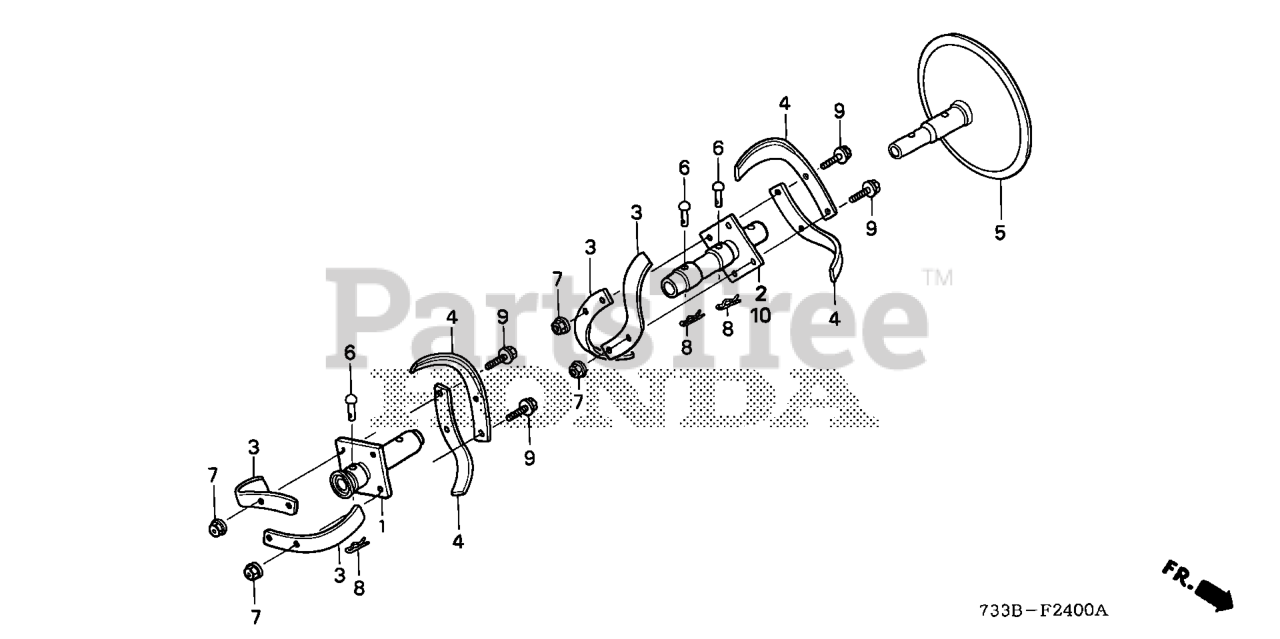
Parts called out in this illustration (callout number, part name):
1	PIPE (INNER)
2	PIPE, R. (OUTER)
3	TINE A, ROTARY
4	TINE B, ROTARY
5	DISK, SIDE
6	PIN (10X53.5)
7	NUT, FLANGE (10MM)
8	PIN, LOCK (10MM) Use from Frame SN 2149606 to 2149605.
9	BOLT, FLANGE (10X25)
10	PIPE, L. (OUTER)
